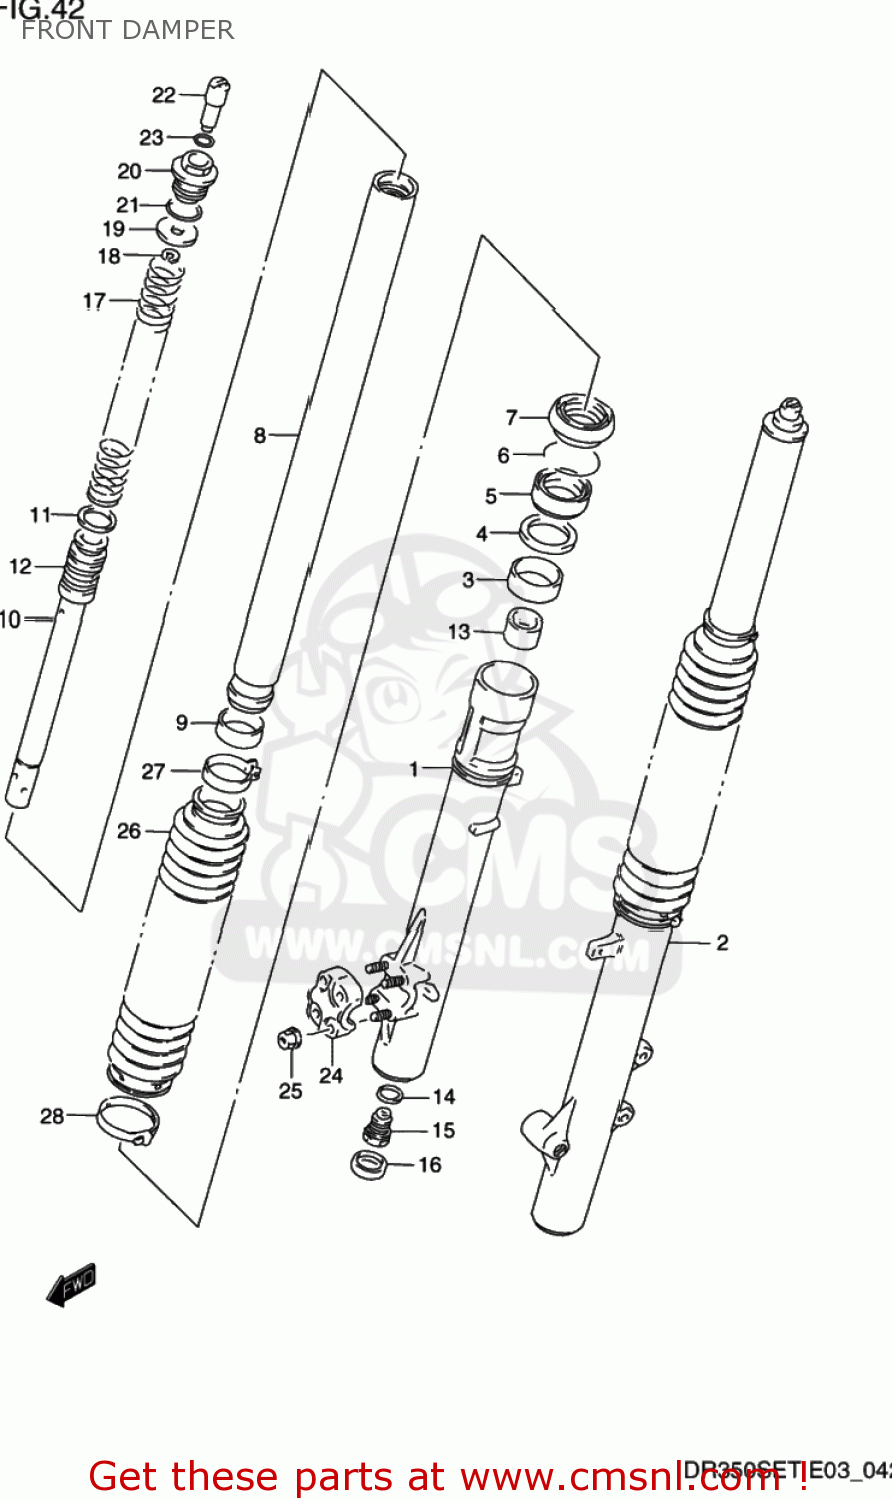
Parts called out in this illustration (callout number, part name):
1	TUBE,OUTER,R
2	TUBE,OUTER,L
3	BUSH,GUIDE
4	SPACER,SEAL
5	SEAL,OIL
6	CIRCLIP,FORK OIL SEAL
7	DUST SEAL
8	TUBE,INNER
9	BUSH,SLIDE
10	CYLINDER
11	RING,PISTON
12	SPRING,REBOUND
13	PIECE,OIL LOCK
14	GASKET (NAS)
15	BOLT,LWR
16	CAP,LOWER
17	SPRING,MAIN
18	E RING
19	SEAT,SPRING
20	BOLT,FORK
21	O RING
22	ADJUSTER,SPRING
23	O RING
24	HOLDER,AXLE
25	NUT,HOLDER
26	BOOT
27	BAND,BOOT UPR
28	BAND,BOOT LWR
